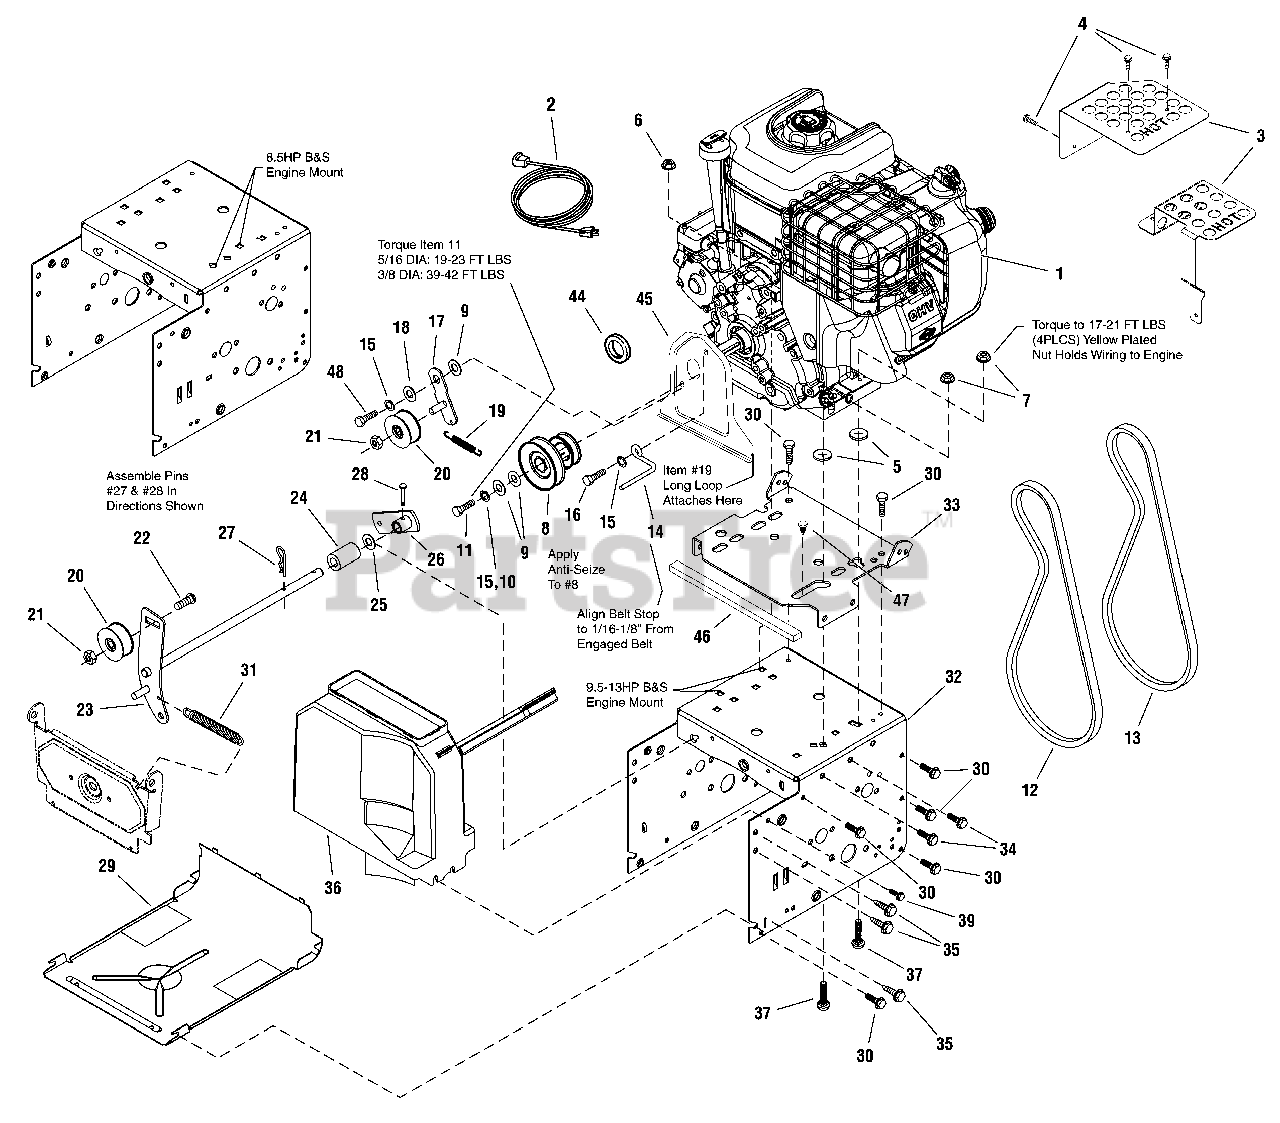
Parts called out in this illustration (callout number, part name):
1	* ENGINE, 11.5GT Briggs & Stratton
1	* ENGINE, 13.5GT Briggs & Stratton
1	* ENGINE, 14.5GT Briggs & Stratton
1	* ENGINE, 15.5GT Briggs & Stratton
2	CORD, Electric Start
3	GUARD, Muffler
4	SCREW, Hex Washer Head Taptite #10 x 1/2
5	NUT, Push for 1/4 Diameter Thread
6	NUT, Hex Flange 5/16-18 Whiz Lock Small
7	NUT, Hex Flange 5/16-18 Esna
8	PULLEY, Engine
9	WASHER, 3/8
9	WASHER, 5/16
10	LOCKWASHER, Spring 3/8
11	CAPSCREW, Hex Head 3/8-24 x 1-1/4 G8
11	CAPSCREW, Hex Head 5/16-24 x 1-1/4 G8
12	V-BELT, 3L, 33.13 Drive
13	V-BELT, 4L, 38.35 Auger
13	V-BELT, 4L, 36.5 Auger
14	STOP, Belt
15	LOCKWASHER, Spring 5/16
16	CAPSCREW, Hex Head 5/16-24 x 3/4 G5
17	BRACKET & WELD PIN ASSEMBLY, Idler
18	BUSHING, Idler Bracket
19	SPRING, Extension Idler
20	IDLER, Plastic Ball Bearing
21	NUT, Hex Centerlock Jam 3/8-16
22	CARRIAGE BOLT, 3/8-16 x 1-1/4 G5
23	IDLER, Auger Assembly
25	WASHER, 1/2
26	ARM, Control Powdered Metal
27	PIN, Hair
28	PIN, Clevis
29	PANEL, Bottom
30	SCREW, Hex Washer Head Taptite 1/4-20 x 5/8
31	SPRING, Extension Auger Idler
32	FRAME, EZ Turn Axle
32	FRAME, 7.5-11.5GT B&S
33	PLATE, Engine Mount 11GA
34	SCREW, Hex Washer Head Taptite 5/16-18 x 1/2
35	SCREW, Hex Washer Head Taptite 5/16-18 x 3/4
36	COVER, Belt w/Toolbox B&S
37	CARRIAGE BOLT, 5/16-18 x 1-1/2
39	SCREW, 1/4-AB x 3/4 Hex YZ w/Extension Tooth Washer
45	PLATE, Seal
47	CLIP, Pine Tree
48	BOLT, Hex 5/16-24 x 1
